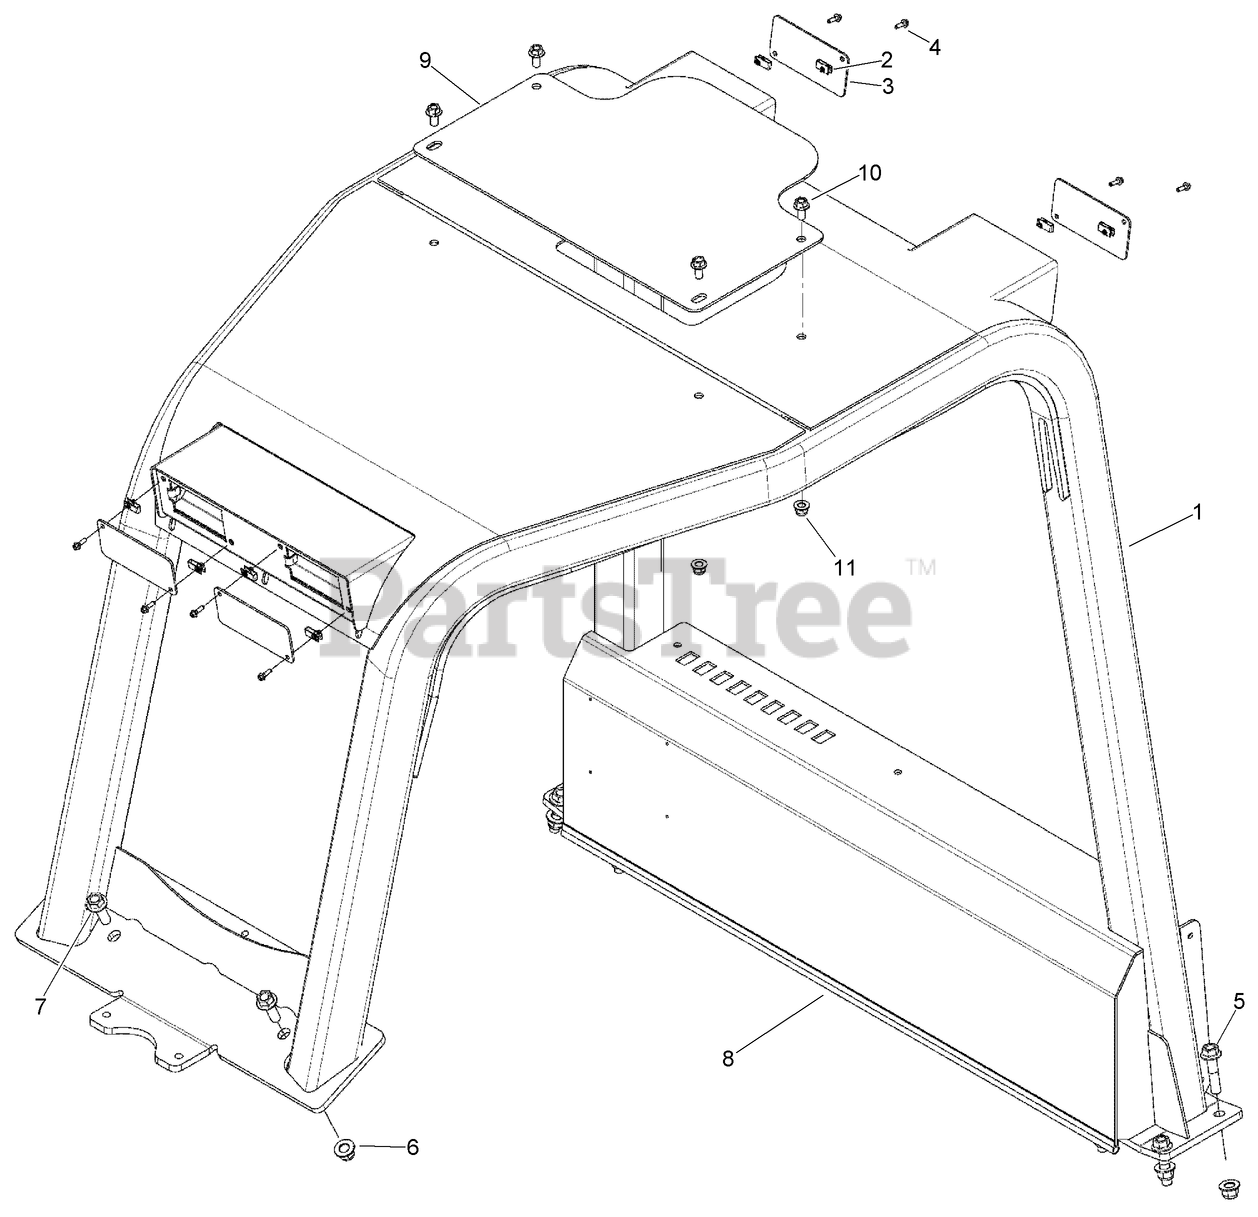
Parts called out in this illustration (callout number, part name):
1	WELDMENT - Main ROPS
3	PLATE- Cover
4	SCREW-HHF
5	SCREW-FLANGE
6	NUT-HHF
7	SCREW-FLANGE
8	SEAL-HOOD
9	PLATE - Cover
10	SCREW-HHF
11	NUT-HHF, LOCK
